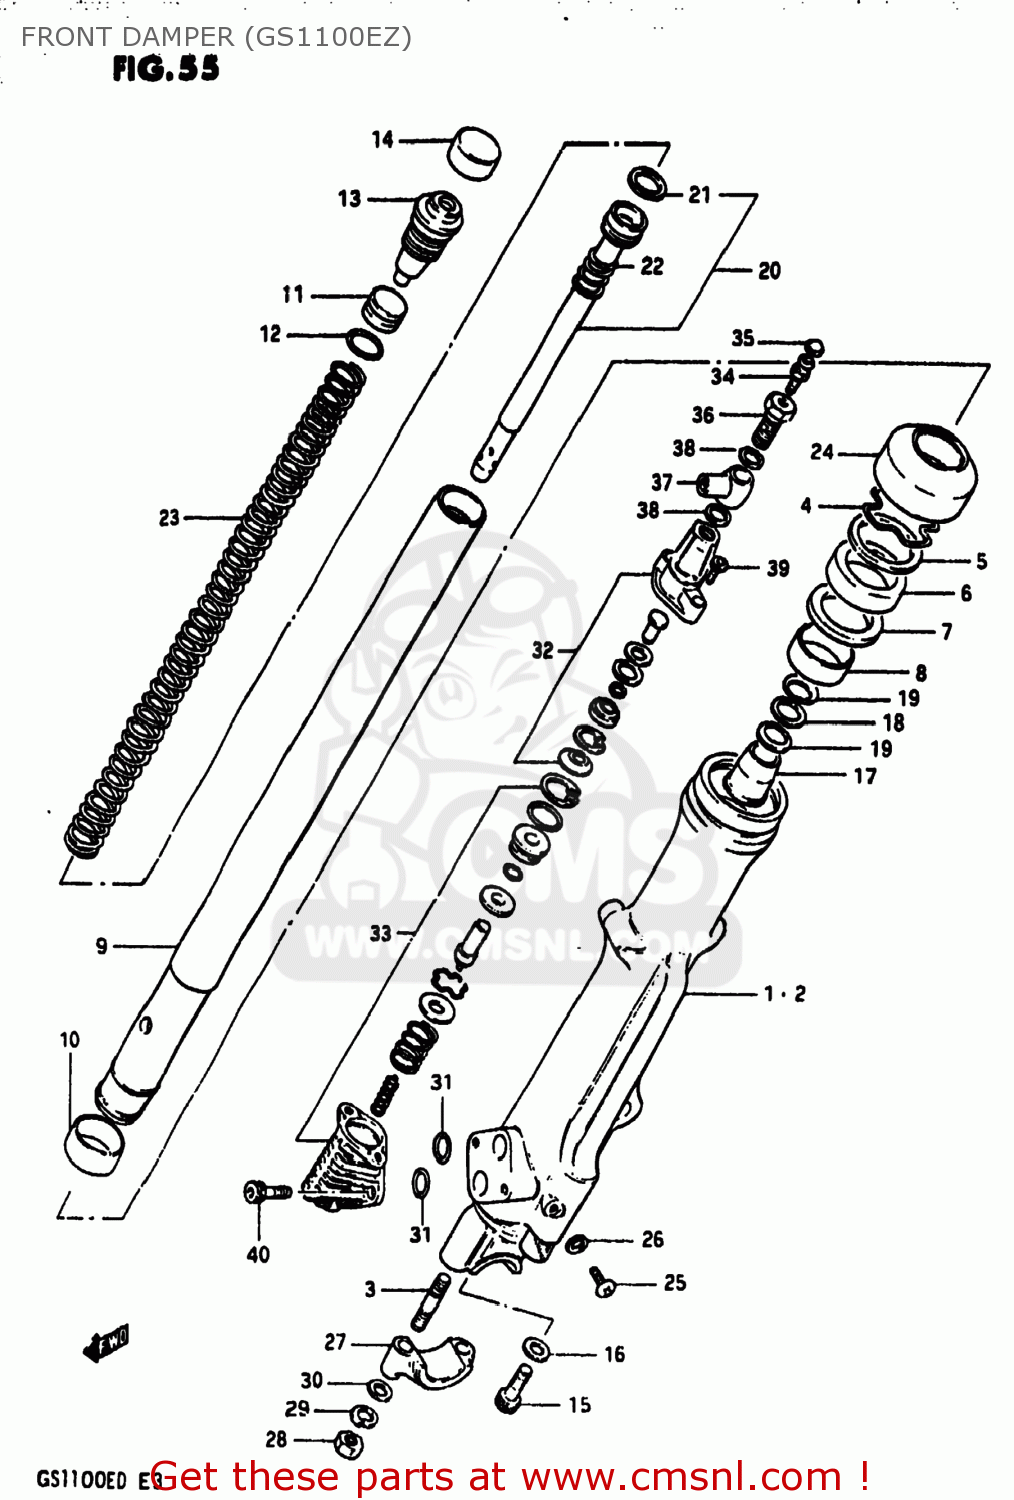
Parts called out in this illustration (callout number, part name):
0	DAMPER ASSEMBLY,LEFT
1	TUBE,FORK,OUTER,RIGHT
2	TUBE,OUTER,LEFT
3	STUD 8X30
4	RING,STOPPER
5	WASHER. FRONT FORK
6	OIL SEAL,FRONT FORK
7	WASHER
8	METAL,SLIDE
9	TUBE,FORK,INNER
10	METAL,FRONT FORK PISTON
11	PISTON,FREE
12	O-RING
13	CAP
14	CAP,RUBBER
15	BOLT,FORK CYLINDER(10X25)
16	GASKET (NAS)
17	PIECE,OIL LOCK
18	WASHER
19	SPRING,LEAF
20	CYLINDER,FRONT FORK
21	RING,PISTON
22	SPRING,FORK REBOUND
23	SPRING,FRONT FORK
24	SEAL,DUST
25	SCREW
26	GASKET,DRAIN,PLUG (NAS)
27	HOLDER,AXLE
28	NUT (8MM)
29	LOCK WASHER
30	WASHER
31	O RING
32	MODULATOR PARTS SET,FRONT
33	MODULATOR VALVE SET,FRONT
34	BREATHER,AIR
35	CAP,BREADER
36	BOLT,UNION
37	SPACER,FRONT FORK MODULATOR
38	WASHER
39	BOLT,FR FORK
40	BOLT,FRONT FORK
